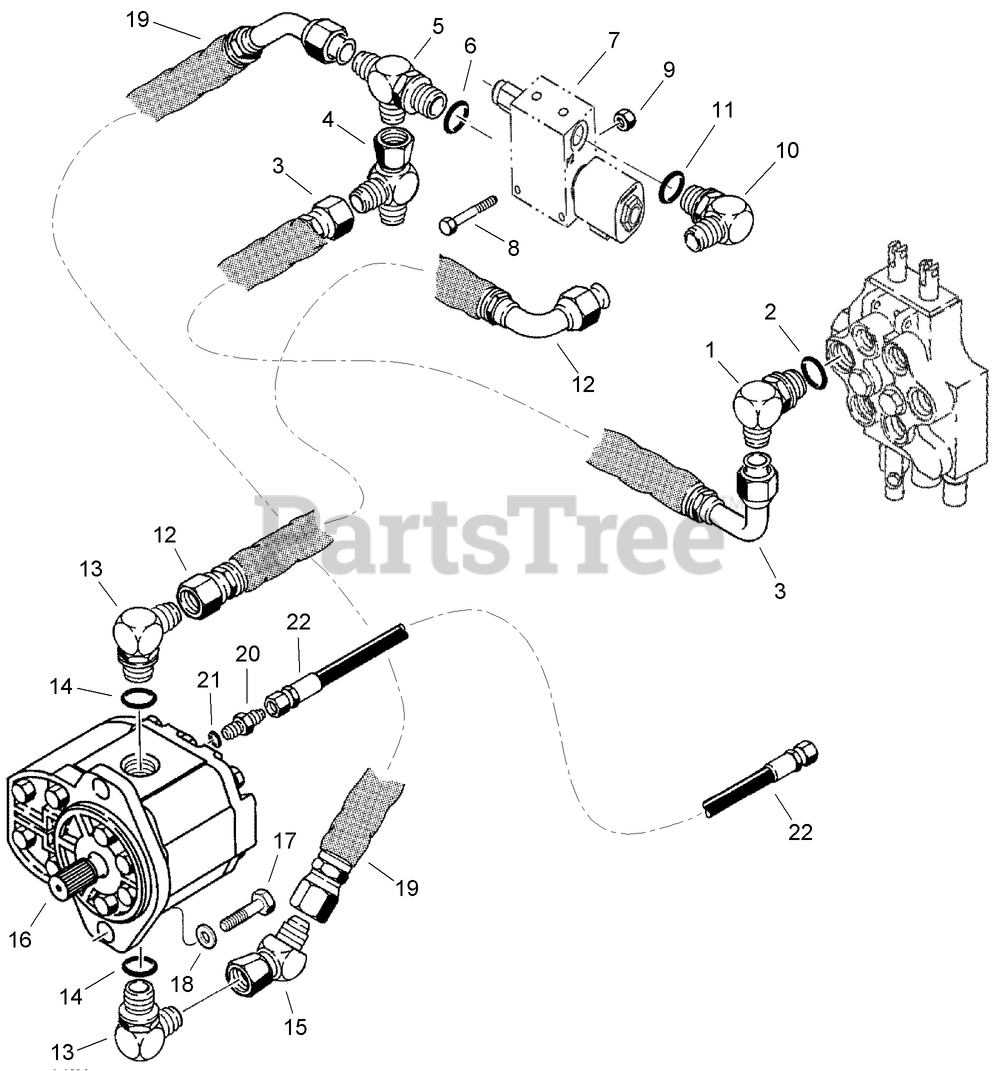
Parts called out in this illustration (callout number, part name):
1	ELBOW-90 Adj 37FL 3/4 x 5/8 Tube
2	O-RING
3	HOSE - 457 mm (18 inch) Long, Plow Lift / Swing Control Valve to Tee
4	FITTING-TEE
5	TEE - 1-1/16-12 Flare Branch x Flare x 7/8-14 inch Adj O-Ring
6	O-RING
7	3 WAY HYD PLOW VALVE ASM
8	BOLT-Hex Hd 0.312 x 2.00 GR8 ZND
9	NUT-HEX
10	ELBOW-90 Adj 37FL 3/4 x 5/8 Tube
11	O-RING
12	HOSE - 1143 mm (45 inch) Long, Control Valve to Upper Port of Plow Motor
14	O-RING - 1-11/64 ID x 7/64 inch Wide
15	ELBOW-45 Deg 12MJ x 12FJ
16	MOTOR ASSEMBLY - Plow
17	SCREW-HH
19	HOSE - 1143 mm (45 inch) Long, Plow Motor to Control Valve
20	CONNECTOR-Str Thd 3/8, 37FL-ORB 3/8
22	ASSEMBLY - Hose
